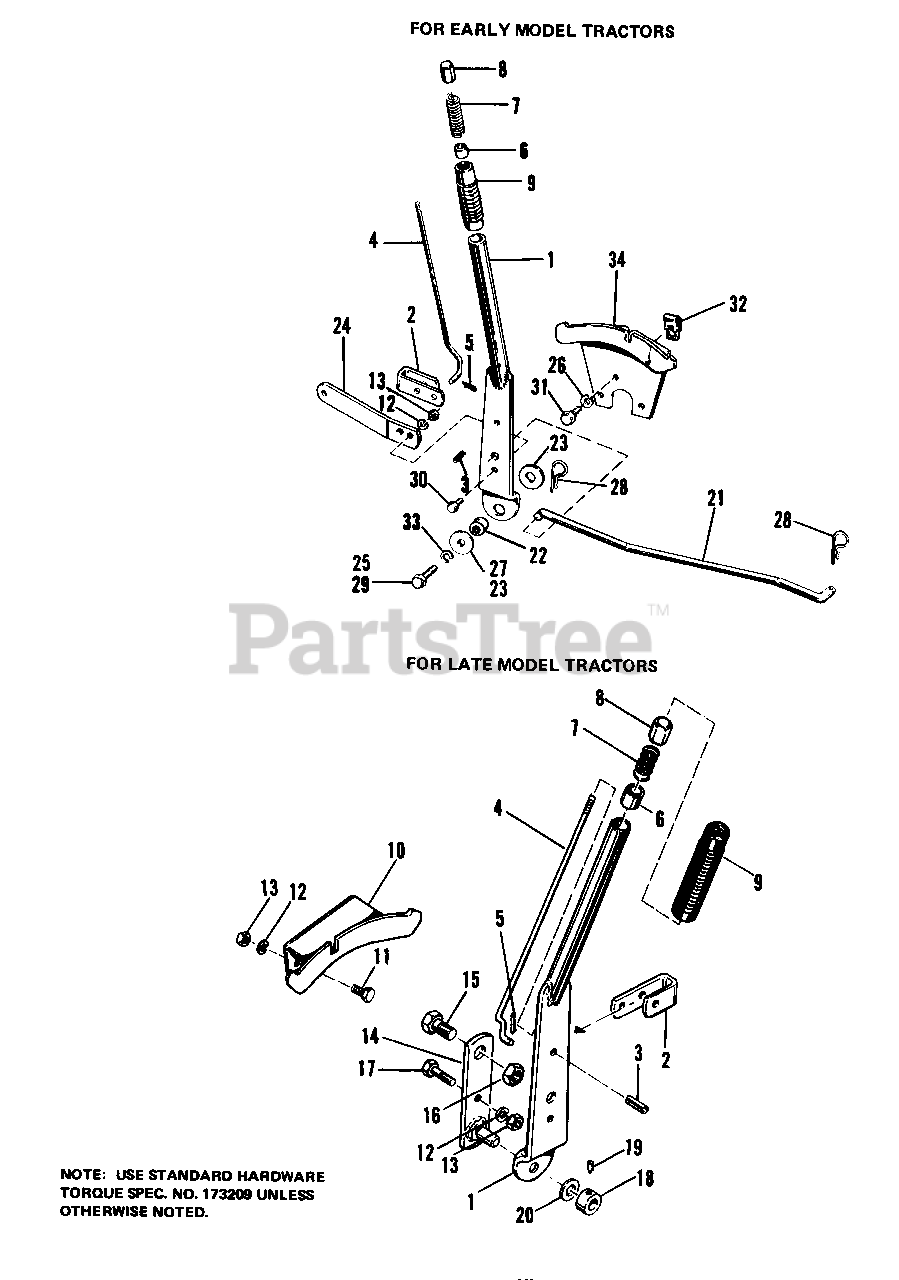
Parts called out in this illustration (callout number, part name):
1	LEVER ASSY, Lift, R.H.
2	LATCH, Lift Lever
3	PIN, Spring, 3/8 x 1
4	ROD, Latch, R.H.
5	PIN, Cotter, 3/32 x 3/4
8	BUTTON, Thumb
9	GRIP, Handle
10	QUADRANT ASSY
11	CAPSCREW, Hex Hd., 3/8-16 x 3/4
12	LOCKWASHER, Spring, 3/8
13	NUT, Hex, 3/8-16
14	LEVER ASSY
15	CAPSCREW, Hex Hd., 1/2-13 x 1
16	NUT, Hex, Full Lock, Jam, 1/2-13
17	CAPSCREW, Hex Hd., 3/8-16 x 1-1/4
18	COLLAR, Set
19	SETSCREW, Sq. Hd., 5/16-18 x 3/8
20	WASHER, Plain, 1/2
21	ROD, Lift
23	WASHER, Plain
24	LEVER, Lift
25	CAPSCREW, Hex Hd., 7/16-14 x 1/2
26	LOCKWASHER, Spring, 5/16
27	WASHER, Plain, 5/16
28	PIN, Quick, 1-7/8
29	CAPSCREW, Hex Hd, 5/16-18 x 5/8
30	CAPSCREW, Hex Hd., 3/8-16 x 7/8
31	CAPSCREW, Hex Hd., 5/16-18 x 3/4
32	NUT, Retainer, 5/16-18
33	LOCKWASHER, Spring, 7/16
34	QUADRANT ASSY, R.H.
